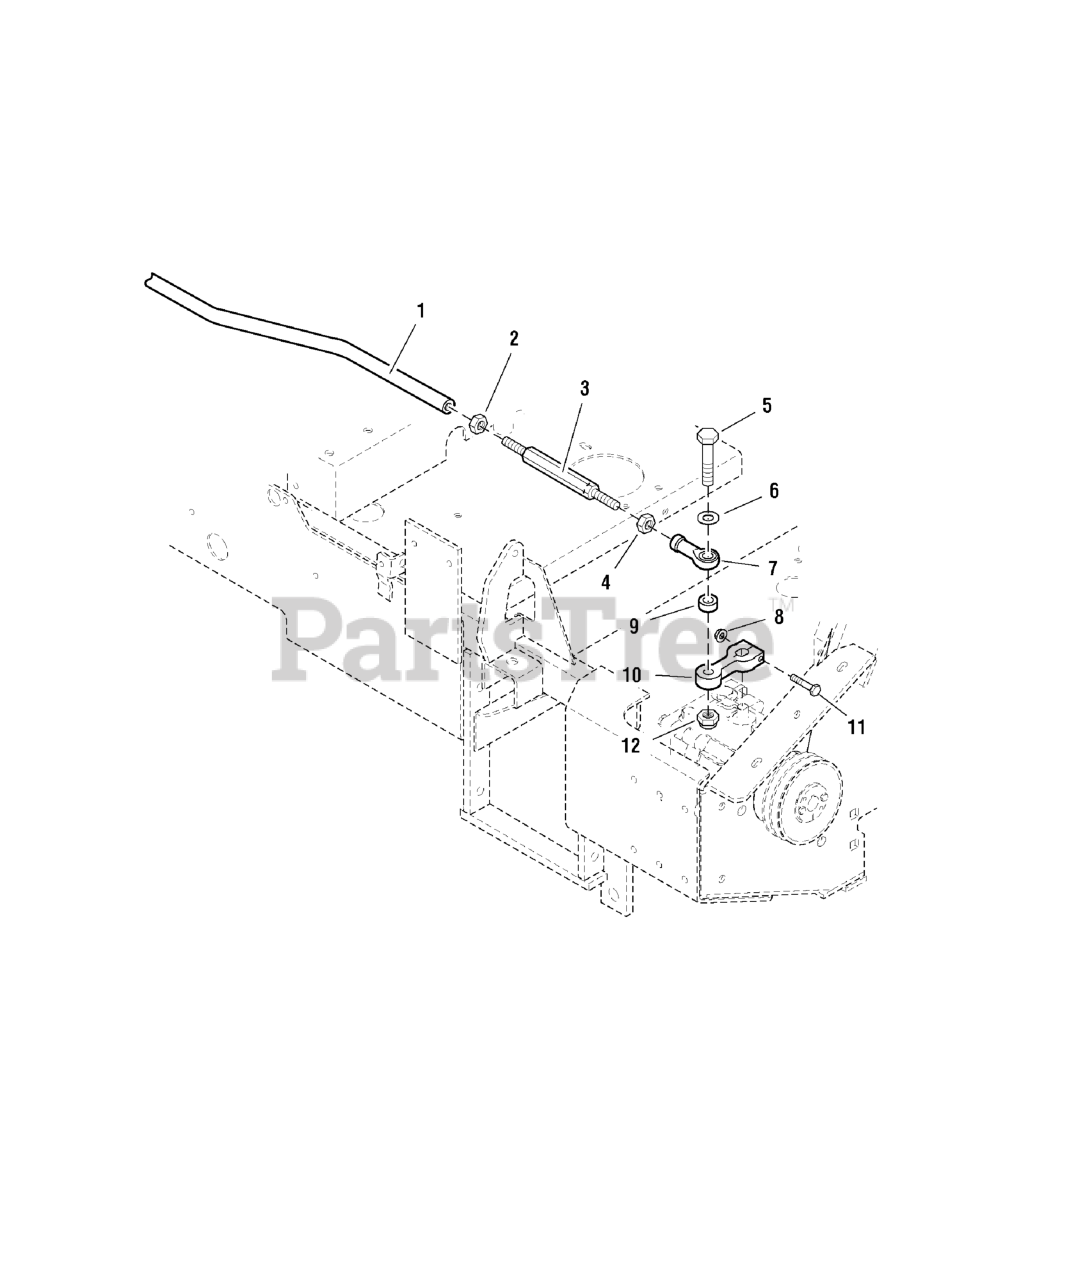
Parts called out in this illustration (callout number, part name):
1	CONTROL ROD
2	NUT, 3/8-24 Hex
3	LINK, Neutral Adjust
4	NUT, 3/8-24 Hex, LH
5	BOLT, 3/8-16 X 2, GD5, CZ
6	WASHER, 3/8 SAE
7	BALL JOINT, 3/8-24 LH, Female
8	NUT, 1/4-20 HEX SERR. FLANGE
9	SPACER, .39 x .75 x .38
10	CONTROL ARM
11	BOLT, 1/4-20 x 1-3/4
12	NUT, 3/8-16 HEX NYLON LOCK
